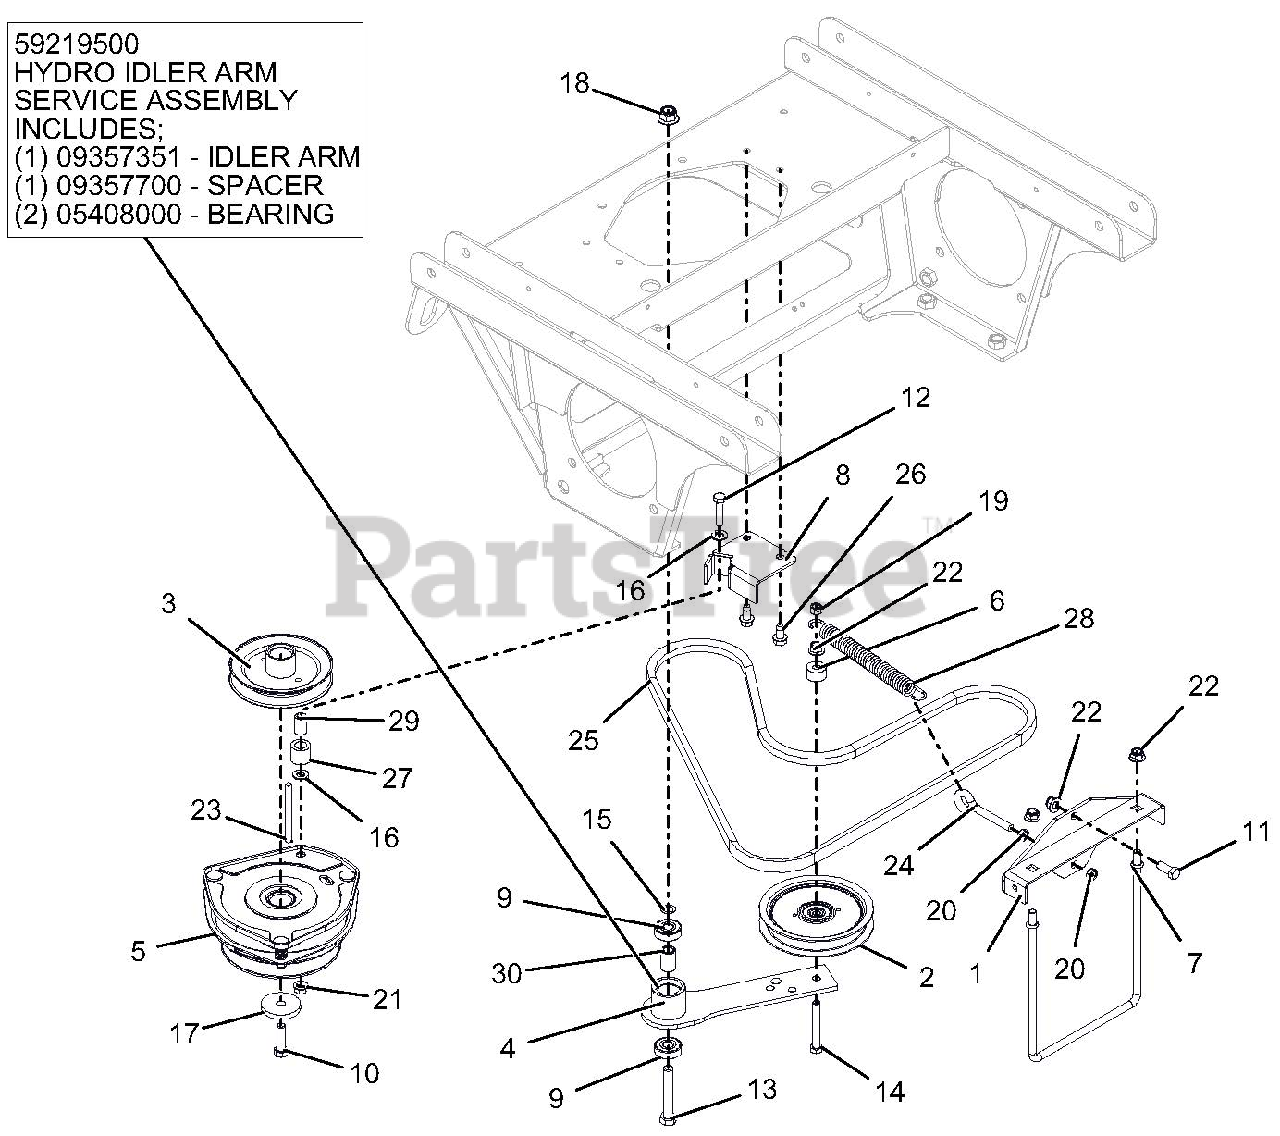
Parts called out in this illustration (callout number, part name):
1	SPRING ANCHOR BRKT WMT - BLACK
2	IDLER, FLAT-5.00X.75
3	SHEAVE-ENGINE 1.127ID X 5.25OD
4	HYDRO DRIVE IDLER ARM WMT- BLK
4	KIT, HYDRO IDLER ARM PT200/400
4	SPACER .510 X .75 X 1.1485
4	BRG-BALL .500X1.38X.437
5	CLUTCH, ELE-OGURA GT3.5-VP01R
6	SPACER .390X1.000X.562
7	ROD, BRAKE MTG
8	CLUTCH STOP WLDMT - BLACK
9	BRG-BALL .500X1.38X.437
10	BLT-HEX .44-20X1.50 G5 YZ EP80
11	@BLT-HEX .38-16X1.00 GR5 YWZC
12	@BLT-HEX .38-16X1.50 GR5 YWZC
13	@BLT-HEX .50-13X3.00 GR5 YWZC
14	@BLT-HEX .38-16X2.75 GR5 YWZC
15	WASHER, .500X.750X.020 THRUST
16	@WSHR-FL-STL.406X.812X.065 YWZ
17	WSHR-FL-STL .469X2.00X.25 YWZC
18	@NUT-LK-NYL-FLG .50-13 YWZC
19	@NUT-LK-CTR .38-16 YWZC
20	NUT-HEX-JAM .375-16 YWZC
21	@NUT-LK-TOP-FLG .38-16 YWZC
22	@NUT-LK-NYL-FLG .38-16 YWZC
23	KEY-SQ. .25X3.50X.25 SAE
24	BLT-EYE .375-16X2.50 YWZC
25	V-BELT, COGGED B-RAW EDGE
26	@SCR-TAP .38-16X.75 HWH TR YWZ
27	BUMPER,RUBBER .62X1.0X.88 LG
28	SPRING, EXTENSION
29	BUSH.,S.391X.622X.950 ST
30	SPACER .510 X .75 X 1.1485
